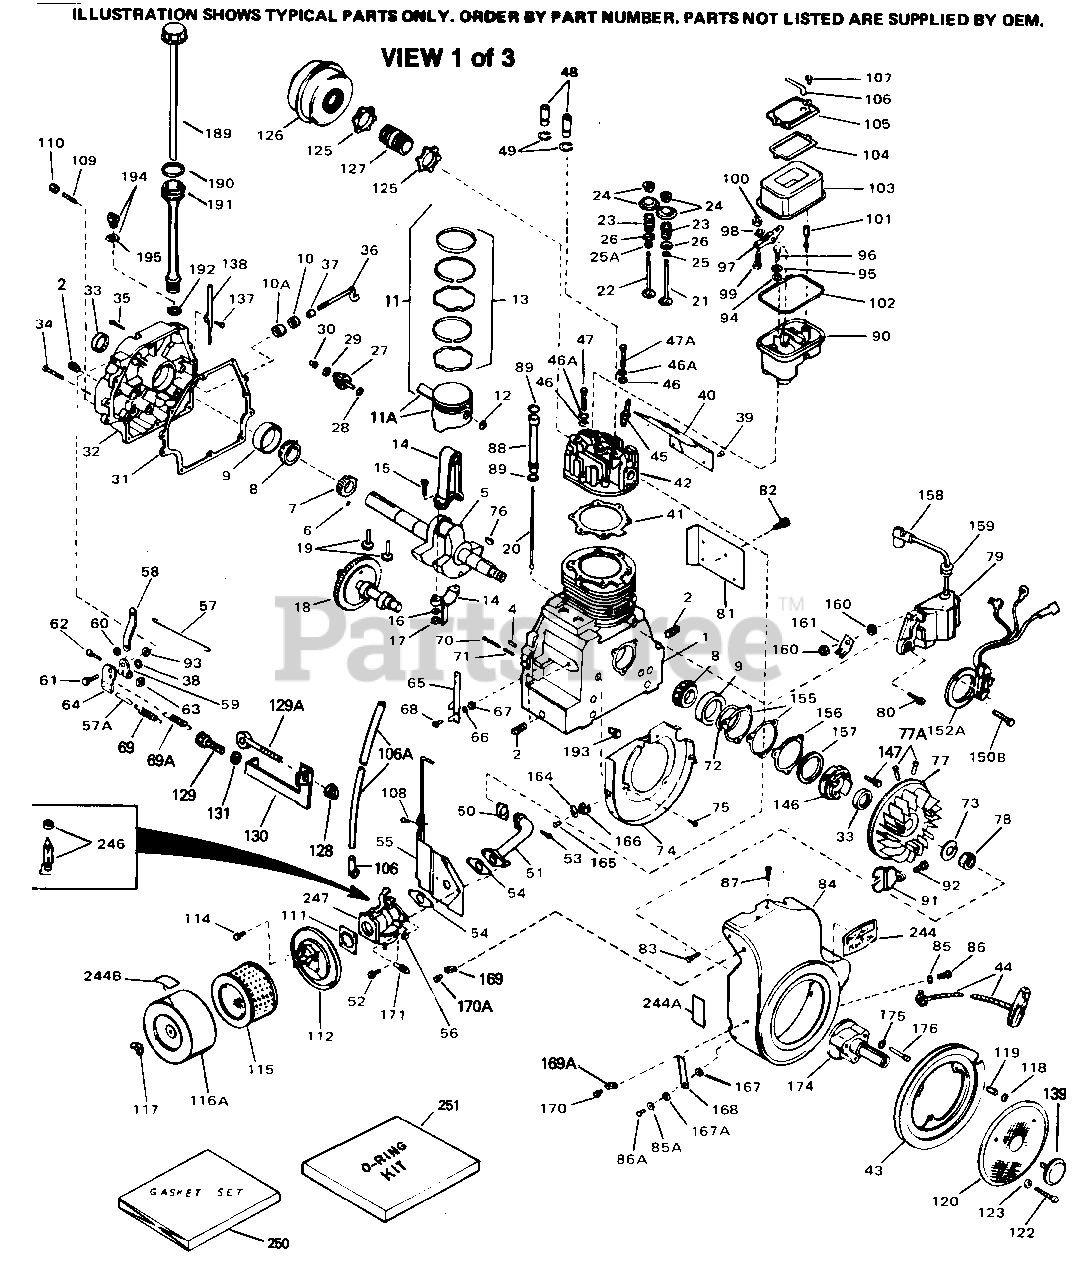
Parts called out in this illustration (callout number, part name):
1	"Cylinder (Incl. 2, 4 & 33) 3-1/8" Bo re
2	Pipe Plug (3/4-14 sq.hd.)(As req.) Bu y local
2	Pipe Plug (1/8-27 sq. hd.) Use as req uired
2	Oil Drain Plug (3/8-18) s req.)
2	Oil Drain Plug As req
2	Pipe Plug, 3/8-18 sq. head Use as req uired
4	Dowel Pin
5	Crankshaft (Incl. 6 thru 9) NOTE: Wh en using this crankshaft to repair ol der units equippedwith straight cut c am and governor gears,it will be nece ssary to order 34751 helical governor gear assembly and 34752 helical cams haft in order to the co
6	Pin, Crankshaft gear
7	Gear, Crankshaft (Straight)
8	Bearing, Tapered roller
9	Cup, Bearing
11	Piston, Pin & Ring Set (Std.) 3-1/8" Bore
11	Piston, Pin & Ring Set (.010" OS)
11	Piston, Pin & Ring Set (.020" OS)
11A	Piston & Pin Ass'y. (Std.)(3-1/8") In cl. 12
11A	Piston & Pin Ass'y. (.010" OS) Incl. 12
11A	Piston & Pin Ass'y. (.020" OS) Incl. 12
12	Ring, Piston pin retaining
13	Ring Set (Std.) (3-1/8" Bore)
13	Ring Set (.010" OS)
13	Ring Set (.020" OS)
14	Connecting Rod Assy. (Std.) Incl. 15, 1 6 & 17
14	Connecting Rod Assy. (.010" US) Incl. 1 5,16,17
14	Connecting Rod Assy. (.020" US) Incl. 1 5,16.17
15	Bolt, Connecting rod
17	Nut Assy.
18	Camshaft (MCR) (Straight)
19	Lifter, Valve
20	Rod, Push
21	Intake Valve (Std.)
21	Intake Valve (1/32" OS)
22	Exhaust Valve (Std.)
22	Exhaust Valve (1/32" OS)
23	Spring, Valve
24	Retainer & Cap Set, Keeper valve
25	* "O" Ring (Intake only) Also Incl. in 251
25A	* "O" Ring (Exhaust only) Also Incl. in 251
26	Cap, Valve
27	Governor Gear & Shaft Ass'y. Straigh t
28	Washer, Flat
29	Washer, Flat
29	WASHER
30	Spool, Governor
31	* Gasket, Cylinder cover
32	Cylinder Cover Assy. Incl. 2,33,36,37 & 38
33	* Seal, Oil
34	Screw, 1/4-20 x 1"
35	Screw, 1/4-20 x 2"
36	Rod Assy., Governor
37	Spacer, Governor rod
38	Retaining Ring
39	Screw, 10-16 x 3/8"
40	Cover, Cylinder head
41	* Gasket, Cylinder head
42	Head, Cylinder
43	Pulley, Starter
44	Rope Assy., Starter
45	Spark Plug (L-82C)
46	Washer, Belleville
46A	Washer, Flat
47	Screw, 5/16-18 x 1-3/4"
47A	Screw, 5/16-18 x 1-3/8"
48	Valve Guide Kit (Incl. 49)
49	Ring, Retaining
50	* Gasket, Intake pipe
51	Pipe, Intake
52	Screw, Torx T-30, 5/16-18 x 1-1/8"
53	Screw, 5/16-18 x 7/8"
54	* Gasket, Carburetor
55	Baffle, Air cleaner
56	Nut, Lock 5/16-24 Used in early produ ction
57	Link, Governor lever-to-throttle leve r
58	Lever, Governor
59	Clamp, Governor lever
60	Lockwasher, No. 10 E.T.
61	Screw, 10-32 x 1/2"
62	Screw, Torx T-25, 10-24 x 7/8"
63	Nut, 10-24
64	Plate, Governor spring
65	Lever Assy., Control
67	Bushing, Governor lever
68	Screw, 10-24 x 5/8"
69	Spring, Governor
70	Screw, 10-24 x 2"
72	"O" Ring (Incl. in 251)
73	Washer, Lock
74	Baffle, Blower housing
75	Screw, 1/4-20 x 5/8"
76	Key, Flywheel
77	Flywheel (w/ring gear)
77A	Trigger Pin Kit (Use as required)
78	Nut, Flywheel
79	Solid State Magneto Incl. 158 thru 1 61
80	Screw, 1/4-20 x 3/4"
81	Extension, Blower housing
83	Screw, 1/4-20 x 7/16"
84	Blower Hsg. (Incl. 218A,219) For elec .s tarter
85	Washer, Lock
86	Screw, 5/16-24 x 3/8"
86A	Screw, 5/16-24 x 9/16"
87	Screw, 1/4-20 x 7/16"
88	Push Rod Tube
89	* "O" Ring (Also Incl. in 251)
90	Housing, Rocker arm
91	Cover, Starter bubble
92	Screw, 8-18 x 7/16"
94	* "O" Ring (Also Incl. in 251)
95	Washer, Flat
96	Screw, 1/4-20 x 29/32"
97	Arm, Rocker
98	Ring, Retaining
99	Screw, 1/4-20 x 3/4"
100	Nut, Hex, 1/4-20
101	Stud, Rocker arm
102	* "O" Ring (Also Incl. in 251)
103	Cover, Rocker arm
104	* Gasket, Breather (Also Incl. in 251)
105	Body Assy., Breather
106	Tube, Breather
107	* Screw, 10-32 x 5/8" Also Incl. in 25 1
108	Screw, 1/4-20 x 5/8"
111	* Gasket, Air cleaner
112	Bracket, Air cleaner
114	Screw, 10-32 x 5/8"
115	Air Filter
116A	Cover, Air cleaner
117	Nut, Wing
119	Spacer, Screen
120	Screen, Pulley
122	Screw, 1/4-20 x 1-1/2"
123	Lockwasher
125	Nut, Conduit
126	Muffler
127	Nipple, Exhaust
146	Cover, Cylinder NOTE: Determine the gap between the cover and the machine d surface on the cylinder, which can be from .001" up to .007", in which case no shim gaskets will be required . Use of gaskets must be limited to a combined total of .010"
147	Screw, 5/16-18 x 7/8"
150B	Screw, 10-32 x 5/8"
152A	Stator Plate Assy.
155	* Gasket, Shim (.004/.005 thick) NOTE: Determine the gap between the cover and the machined surface on the cyli nder, which can be from .001" up to . 007", in which case no shim gaskets w ill be required. Use of gaskets must be limited to a combine
156	* Gasket, Shim (.005/.007 thick) NOTE: Determine the gap between the cover and the machined surface on the cyli nder, which can be from .001" up to . 007", in which case no shim gaskets w ill be required. Use of gaskets must be limited to a combine
157	* Spacer, Steel (.010 thick) NOTE: Det ermine the gap between the cover and the machined surface on the cylinder , which can be from .001" up to .007" , in which case no shim gaskets will be required. Use of gaskets must be limited to a combined t
158	Cover, Spark plug
159	Grommet, Lead wire
160	Nut, 8-32
161	Terminal, Female
164	Terminal
165	Screw, 8-32 x 3/8"
166	Breather Tube Grommet
167	Washer, Lock
168	Switch, Stop
169A	Conduit Clip
170	Screw, 10-32 x 3/8"
189	Dipstick (Incl. 190)
190	"O" Ring
191	Tube, Oil filler
193	Wire Clip
244	Decal, Instruction
244A	Decal, Name
246	Valve, Seat & Spring Assy.
247	Carburetor (Incl. 54 & 246) (Refer to Division 5, Section A, page 124 for breakdown) (Refer to Division 5, Sect ion D for breakdown)
250	* Gasket Set (Incl. items marked *)
251	"O" Ring Kit (Incl. Nos. items marked +)
